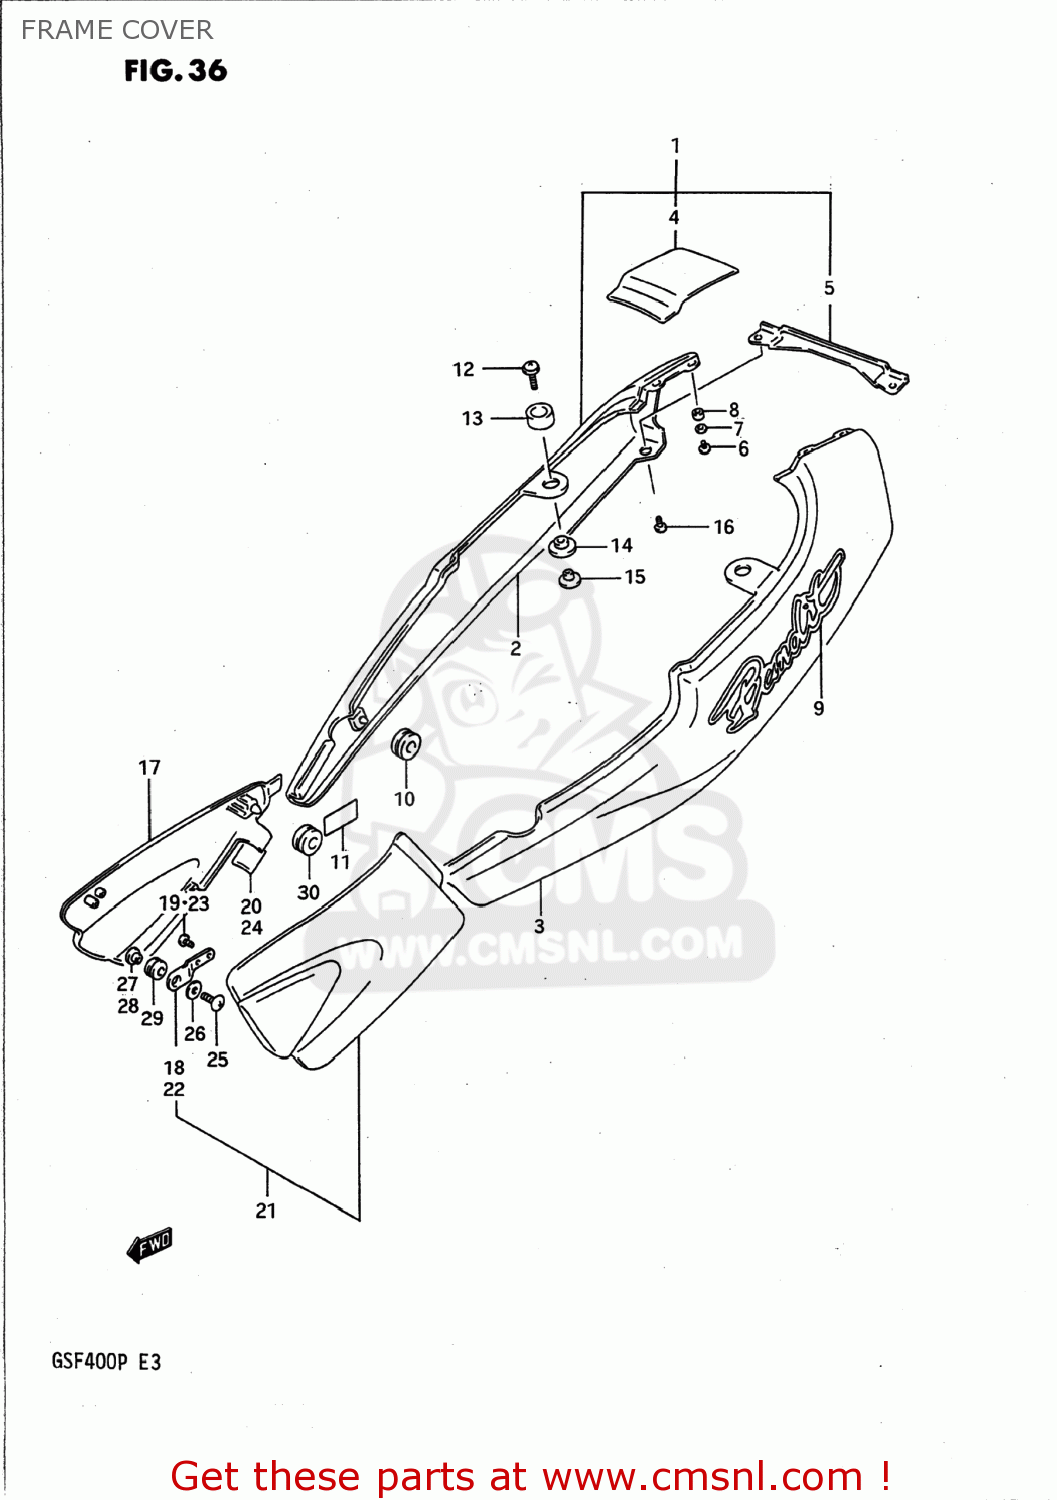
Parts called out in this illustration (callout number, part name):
1	COVER ASSEMBLY,FRAME,RIGHT
2	COVER,FRAME,R(RED)
3	COVER,FRAME,L(RED)
4	COVER,FRAME RR
5	COVER,FRAME,REAR,LOWER
6	SCREW
7	WASHER
8	SPACER,RR COVER
9	EMBLEM,FRAME COVER
10	CUSHION
11	PROTECTOR,FRAME COVER
12	SCREW(6X25)
13	CUSHION,TAIL COVER UPR
14	CUSHION,TAIL COVER LWR
15	SPACER,SEAT TAIL COVER
16	SCREW (5X20)
17	COVER COMP,AIR CLEANER,RIGHT
18	PLATE,AIR CLEANER COVER
19	SCREW
20	CUSHION
21	COVER COMP,AIR CLEANER,LEFT
22	PLATE,AIR CLEANER COVER
23	SCREW
24	CUSHION
25	SCREW(6X20)
26	WASHER(6.5X18X1)
27	WASHER
28	WASHER
29	CUSHION
30	CUSHION
